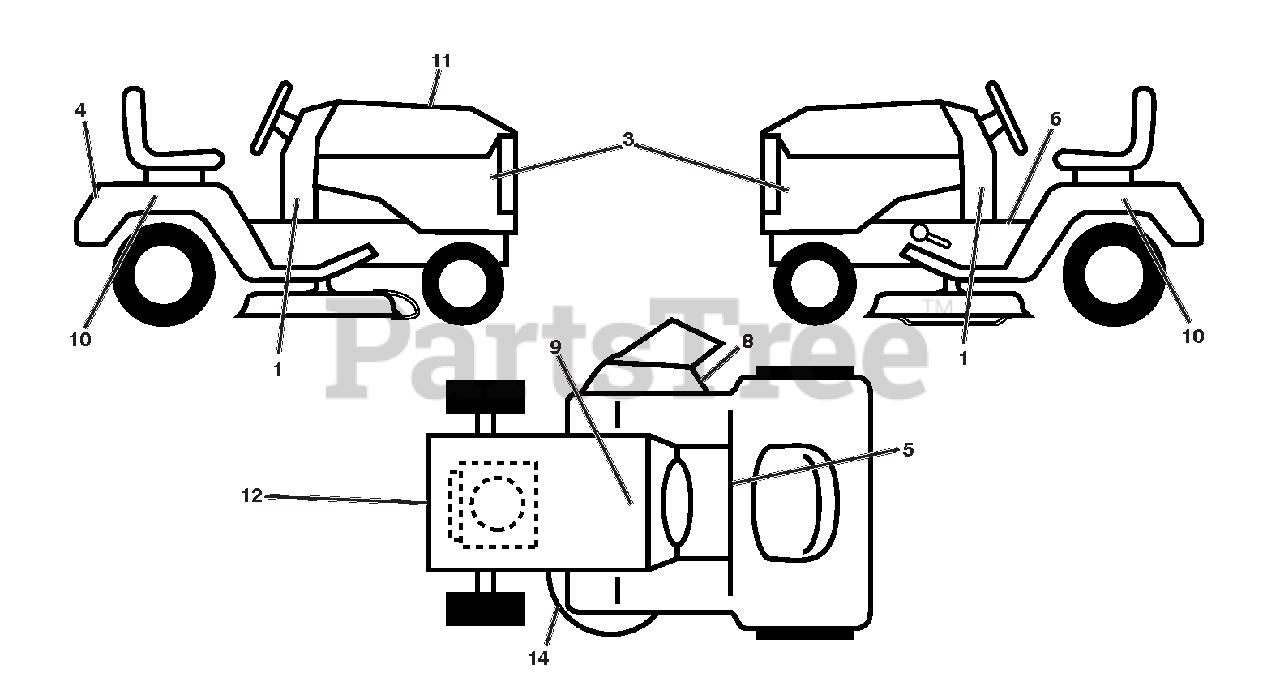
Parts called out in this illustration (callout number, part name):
1	DECAL.DASH
3	DECAL.SDPNL.PWRDBY B&S.ARIENS
4	DECAL.FENDER.REAR.ARIENS
5	DECAL.FENDER
6	DECAL.WARNING.START
8	DECAL.WARNING.KEEP.HAND.AWY
9	DECAL.BAT.DAN/POI P/L SYM.WPN
10	DECAL.FENDER.SIDE.HYDRO
11	DECAL.REPLACEMENT
12	DECAL.ENGINE
14	DECAL.V-BELT.SCH.
